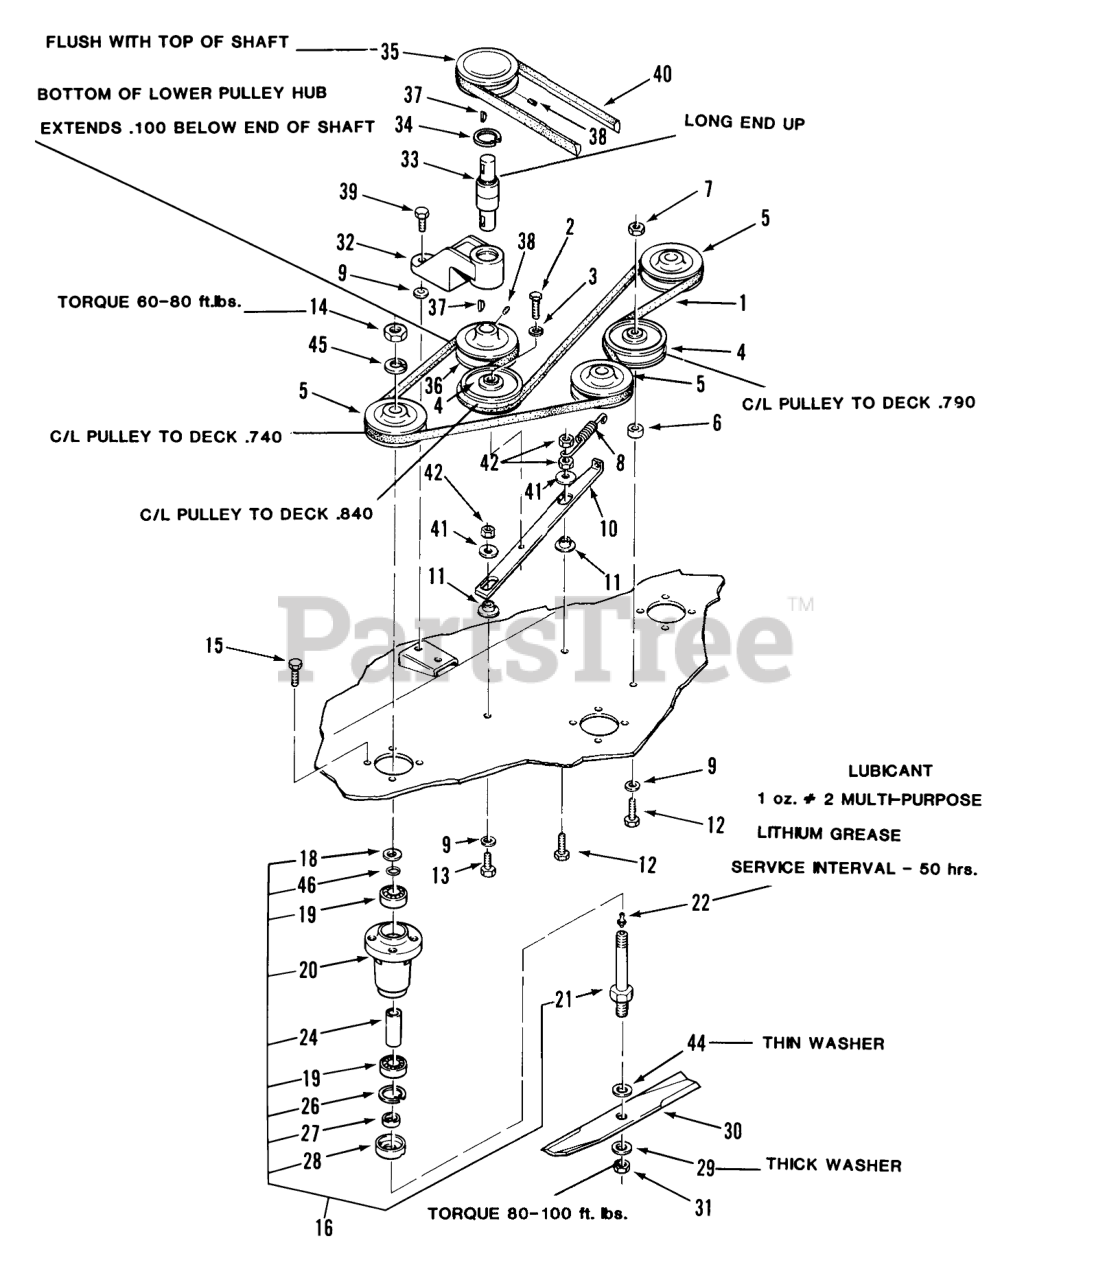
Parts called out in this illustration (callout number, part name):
1	BELT-V
2	BOLT HEX SPECIAL
3	LOCKWASHER
4	Idler Pulley
5	PULLEY
6	SPACER
7	Nut
8	SPRING-EXTENSION
9	WASHER
10	BAR-IDLER SUPPORT
11	SPACER-BUSHING
12	Bolt
13	Bolt
14	Jam Nut
15	Bolt
16	ASSY 36" SPINDLE
18	Washer
19	BEARING-BALL
20	HOUSING-SPINDLE
21	Spindle Shaft
22	Zerk
24	Spacer
26	Ring-Snap
27	SPACER-BLADE
28	CUP-SPINDLE
29	SpeciaI Washer
30	S/A BLADE KIT
31	Nut-Jam
32	HOUSING DRIVE BRG R
33	BEARING-INT SHAFT
34	Snap Ring
35	PULLEY
36	PULLEY-SPLIT
37	KEY-WOODRUFF
38	Set Screw
39	Bolt
40	V-BELT
41	WASHER
42	NUT
44	Washer
45	Lockwasher
46	O RING
